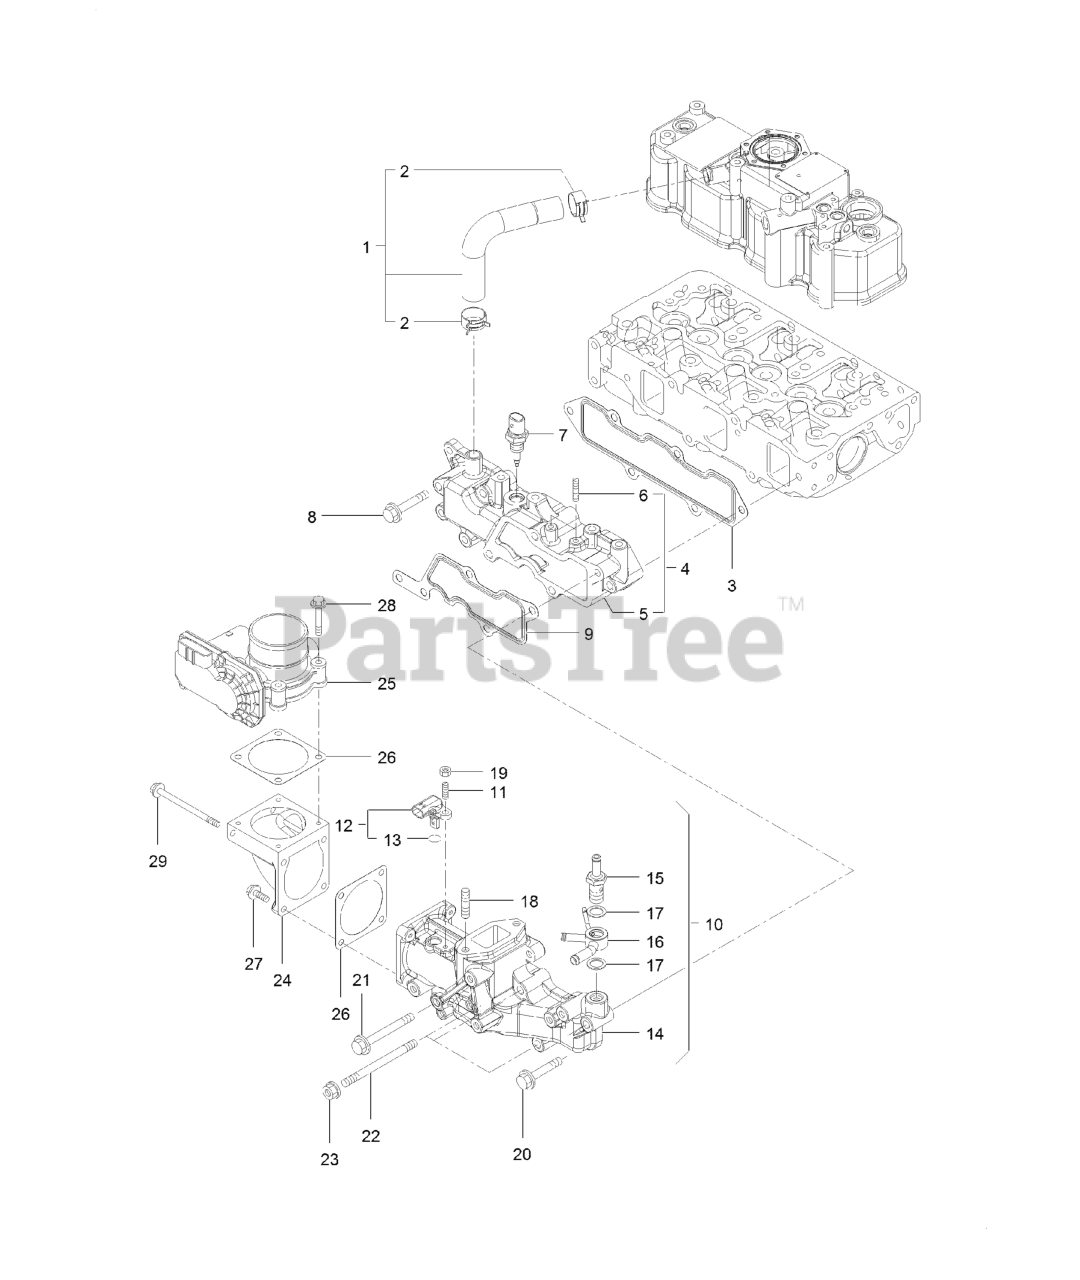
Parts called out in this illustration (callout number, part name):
2	CLIP-HOSE
3	GASKET-MANIFOLD, INTAKE
4	INTAKE MANIFOLD ASM
5	MANIFOLD-INTAKE
7	SENSOR-TEMP, AIR
9	GASKET-COLLECTOR
10	INTAKE COLLECTOR ASM
12	SENSOR-TEMP, AIR
14	COLLECTOR-INTAKE
15	JOINT-HOSE
16	Joint-Hose
17	Washer-Seal
24	Bend-Inlet
25	BODY-THROTTLE
26	GASKET-THROTTLE
